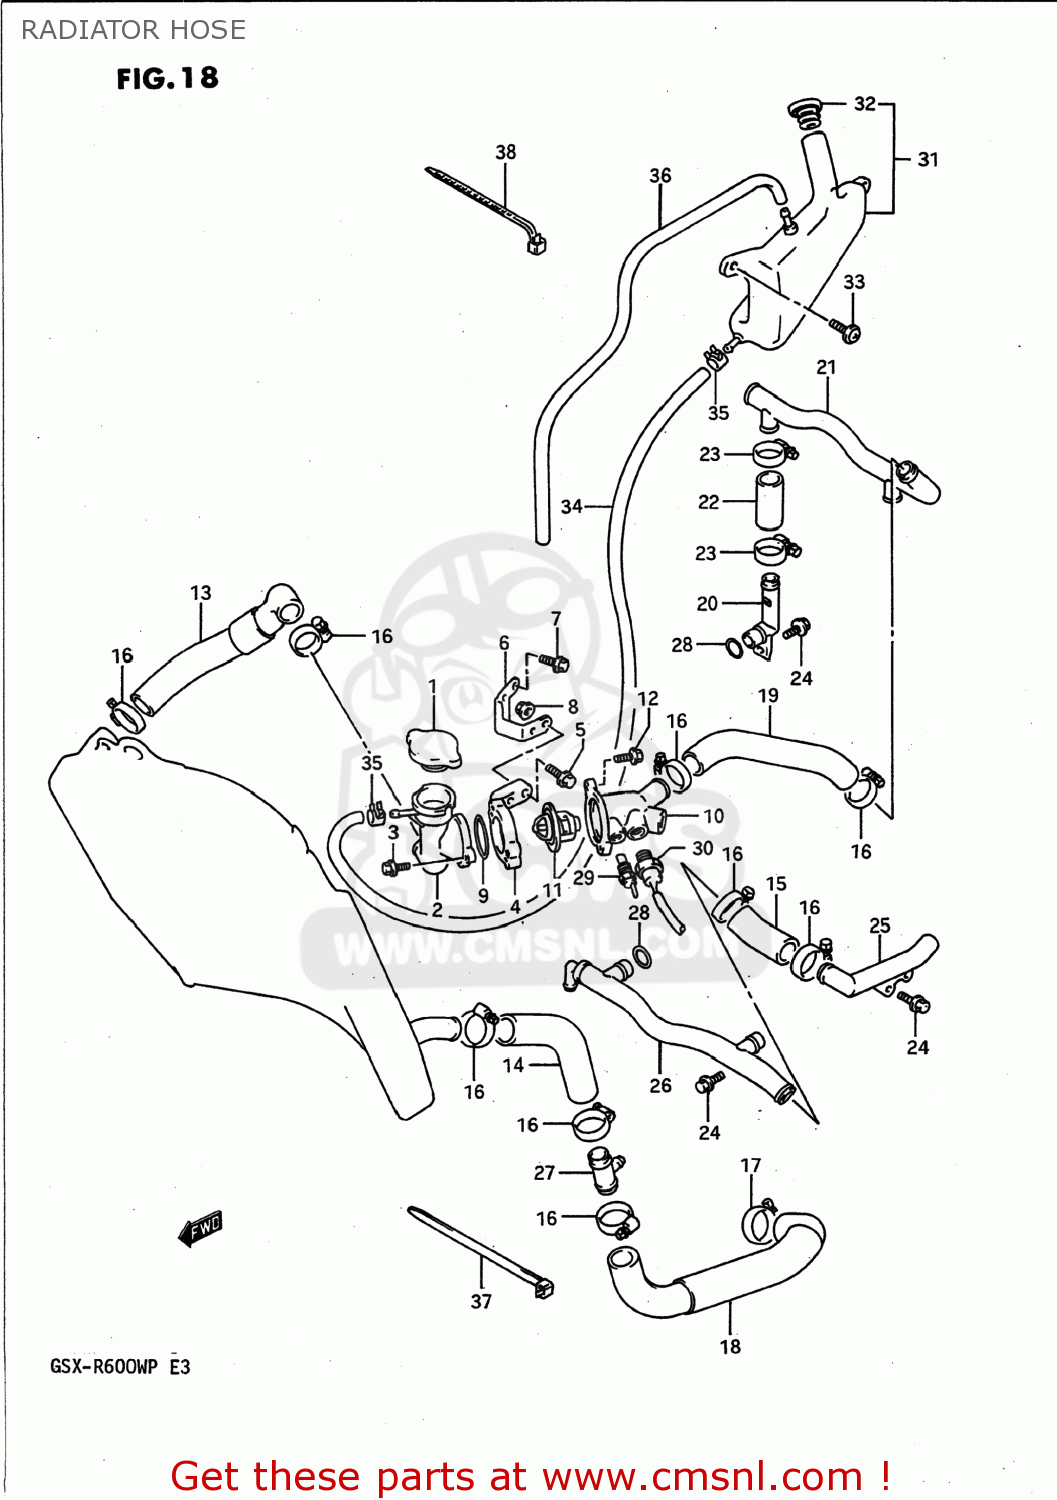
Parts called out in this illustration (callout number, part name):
1	CAP,RADIATOR 1.1
2	CONDUCTION,RADIATOR
3	BOLT 6X16
4	BRACKET,CONDUCTION
5	BOLT 6X20
6	BRACKET,CONDUCTION BRAKE
7	BOLT 6X16
8	NUT
9	O RING(D:2.4,ID:43.2)
10	CONNECTOR,THERMOSTAT INLET
11	THERMOSTAT,WATER
12	BOLT 6X20
13	HOSE,WATER
14	HOSE,RADIATOR OUTLET
15	HOSE,WATER
16	CLAMP
17	CLAMP
18	HOSE,WATER PUMP INLET
19	HOSE,HEAD OUTLET
20	PIPE,HEAD OUTLET
21	PIPE COMP,HEAD OUTLET
22	HOSE,WATER
23	CLAMP
24	BOLT 6X12
25	PIPE,CYLINDER SIDE
26	PIPE COMP,CYLINDER INLET
27	UNION,HOSE JOINT
28	O RING(D:3.2,ID:17.8)
29	TEMP. ZENDER
30	SWITCH COMP,RADIATOR FAN
31	TANK ASSY,RESERVOIR
32	CAP,RESERVOIR TANK
33	SCREW(6X20)
34	HOSE,RESERVOIR TANK INLET
35	CLIP
36	HOSE,RESERVOIR TANK OVERFLOW
37	CLAMP
38	CLAMP(L:165)
